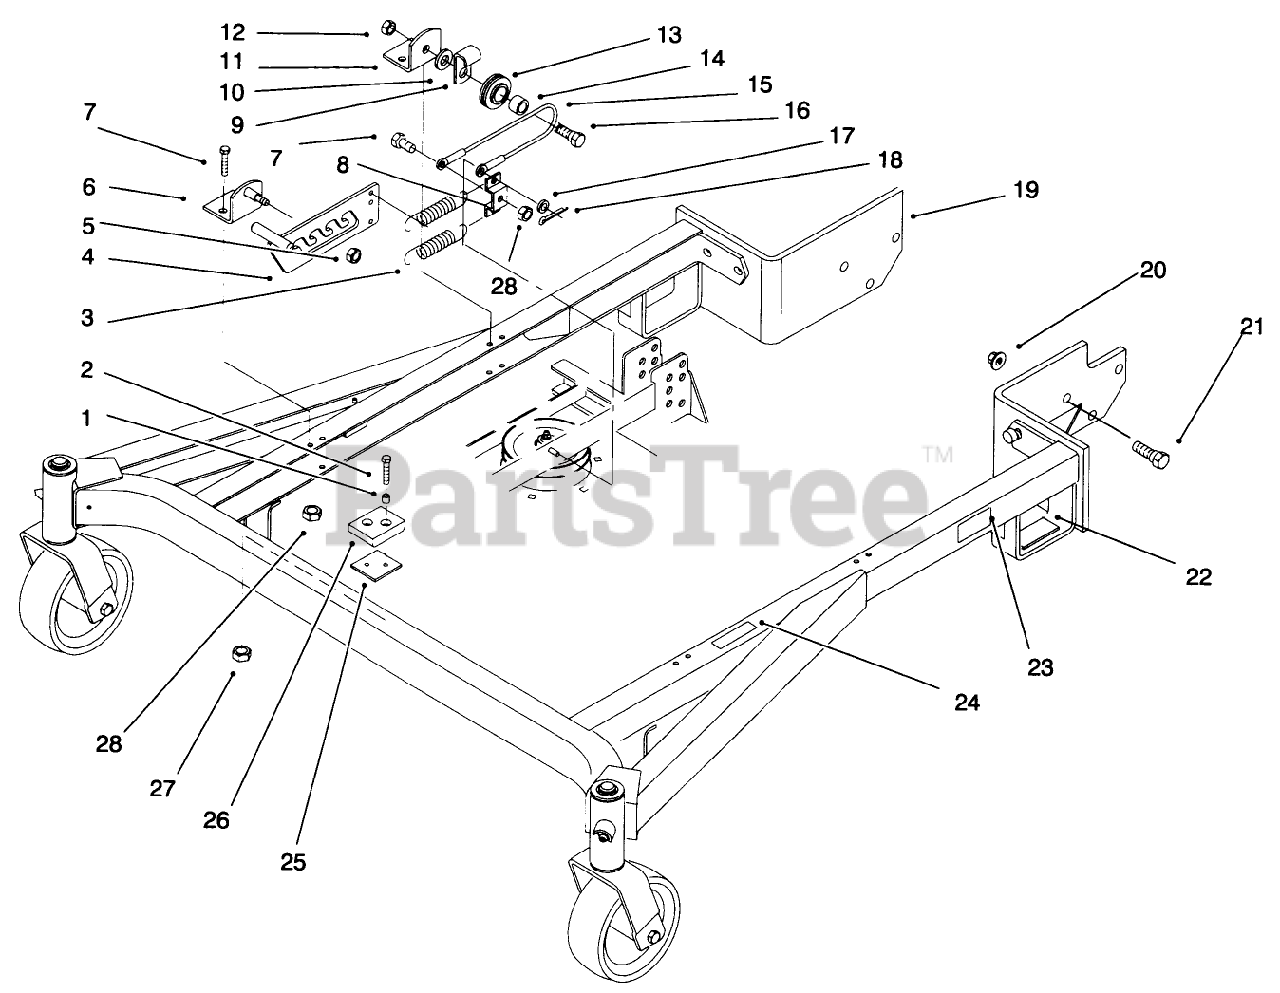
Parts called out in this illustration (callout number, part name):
1	SPACER
3	EXTENSION SPRING
4	Control-Tension
5	NUT-HF
6	Bracket-Control
7	SCREW-HH
8	SPRING BRACKET
9	CABLE RETAINER
10	THRUST WASHER
11	Bracket-Pulley
12	NUT-LOCK, NI
13	Pulley Assembly (Incl. Ref.#14)
14	BUSHING
15	CABLE
16	BOLT-SHOULDER
17	WASHER-FLAT
18	PIN-COTTER
19	Carrier Frame Assembly (Incl. Ref. #23, 24)
20	NUT-HF
21	SCREW-HHF
22	REAR RUBBER PAD
23	DECAL-HOC, LH
24	DECAL-WARNING
25	CUSHING SHIM
26	CUSHION-RUBBER
27	NUT-LOCK, NI
28	NUT-LOCK, NI
